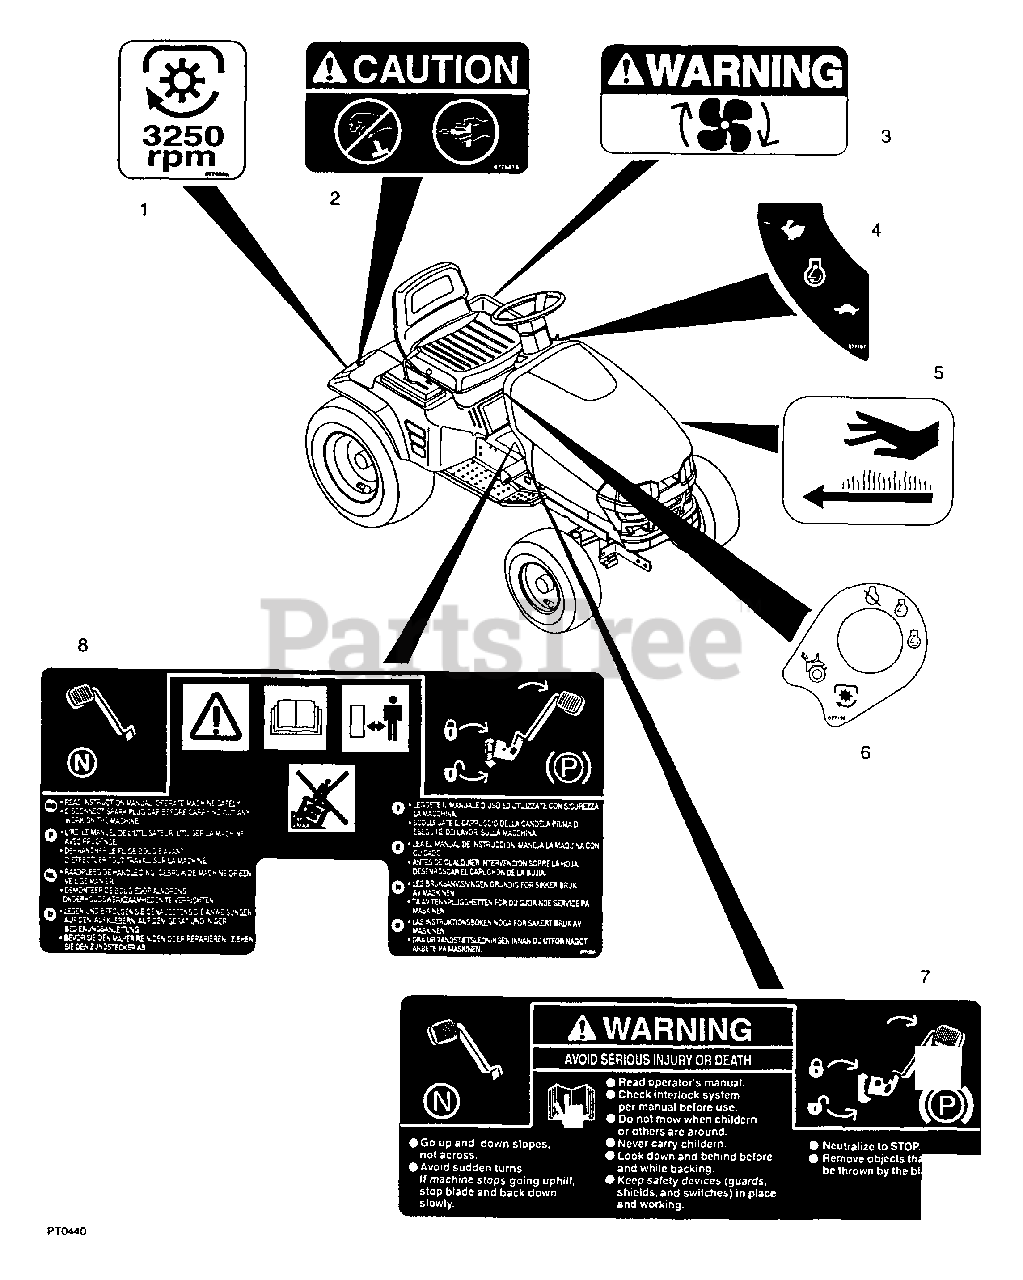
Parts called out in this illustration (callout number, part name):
1	DECAL - PTO SPEED
2	DECAL - CAUTION
3	DECAL - WARNING, FAN
4	DECAL- THROTTLE W/O CHOKE
5	DECAL- HOT SURFACE SYMB.
6	DECAL - IGNITION/PTO
7	DECAL - WARNING, INSTRUCTION
8	DECAL - WARNING INSTRUCTION
